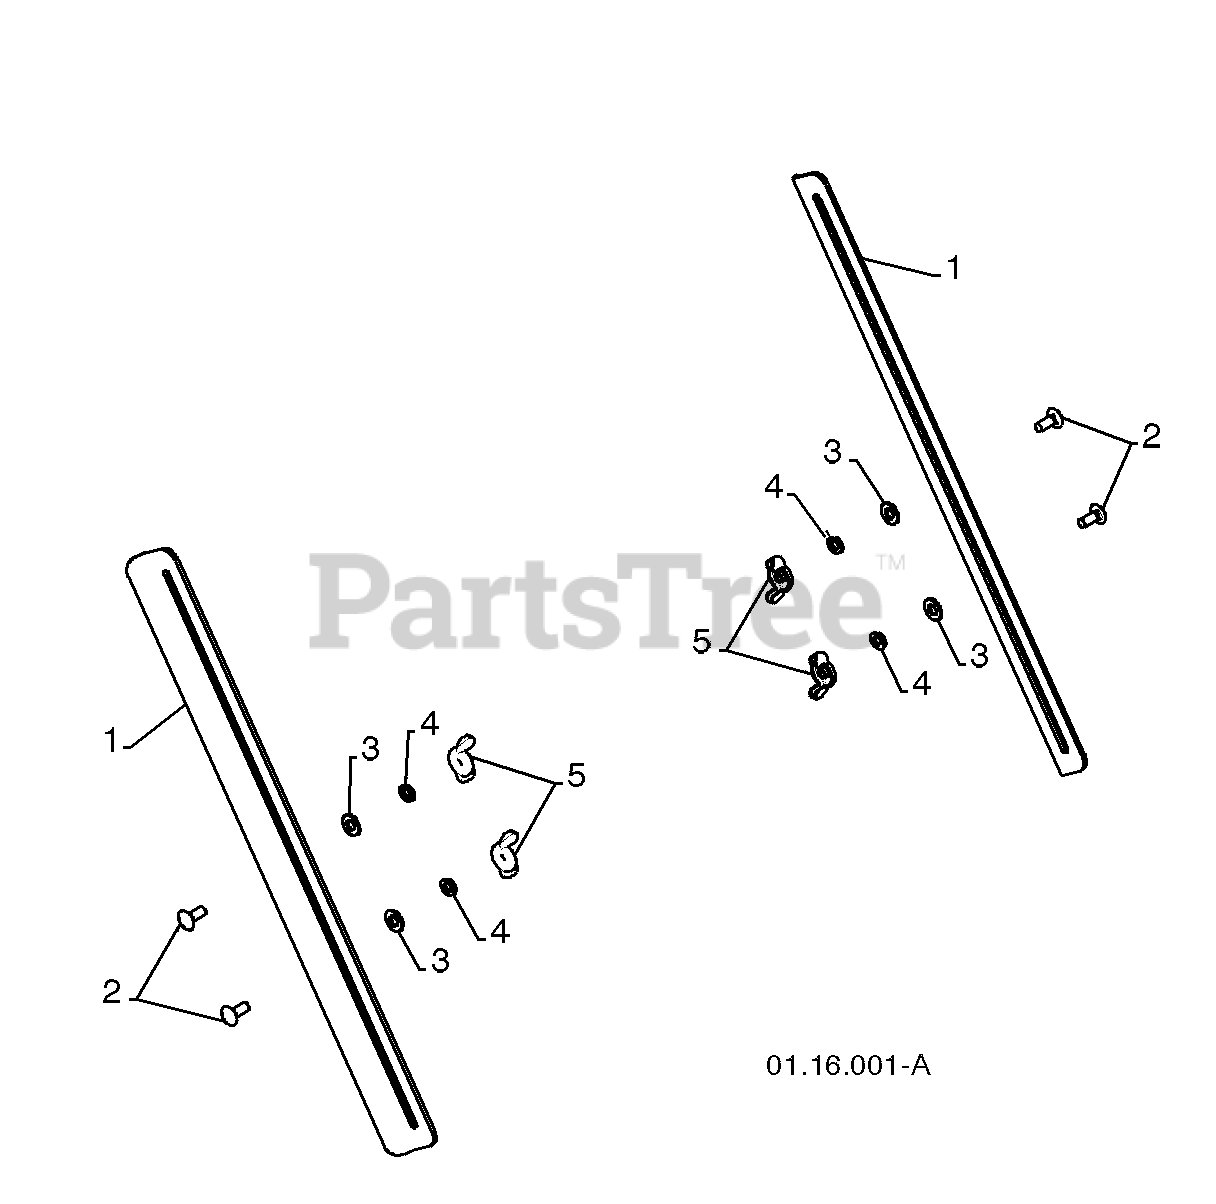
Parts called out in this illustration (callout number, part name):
1	DRIFT CUTTER BAR
2	CARRIAGE BOLT 5/16-18 X .750
3	PLASTIC WASHER
4	LOCKWASHER 5/16
5	NUT 5/16-18
